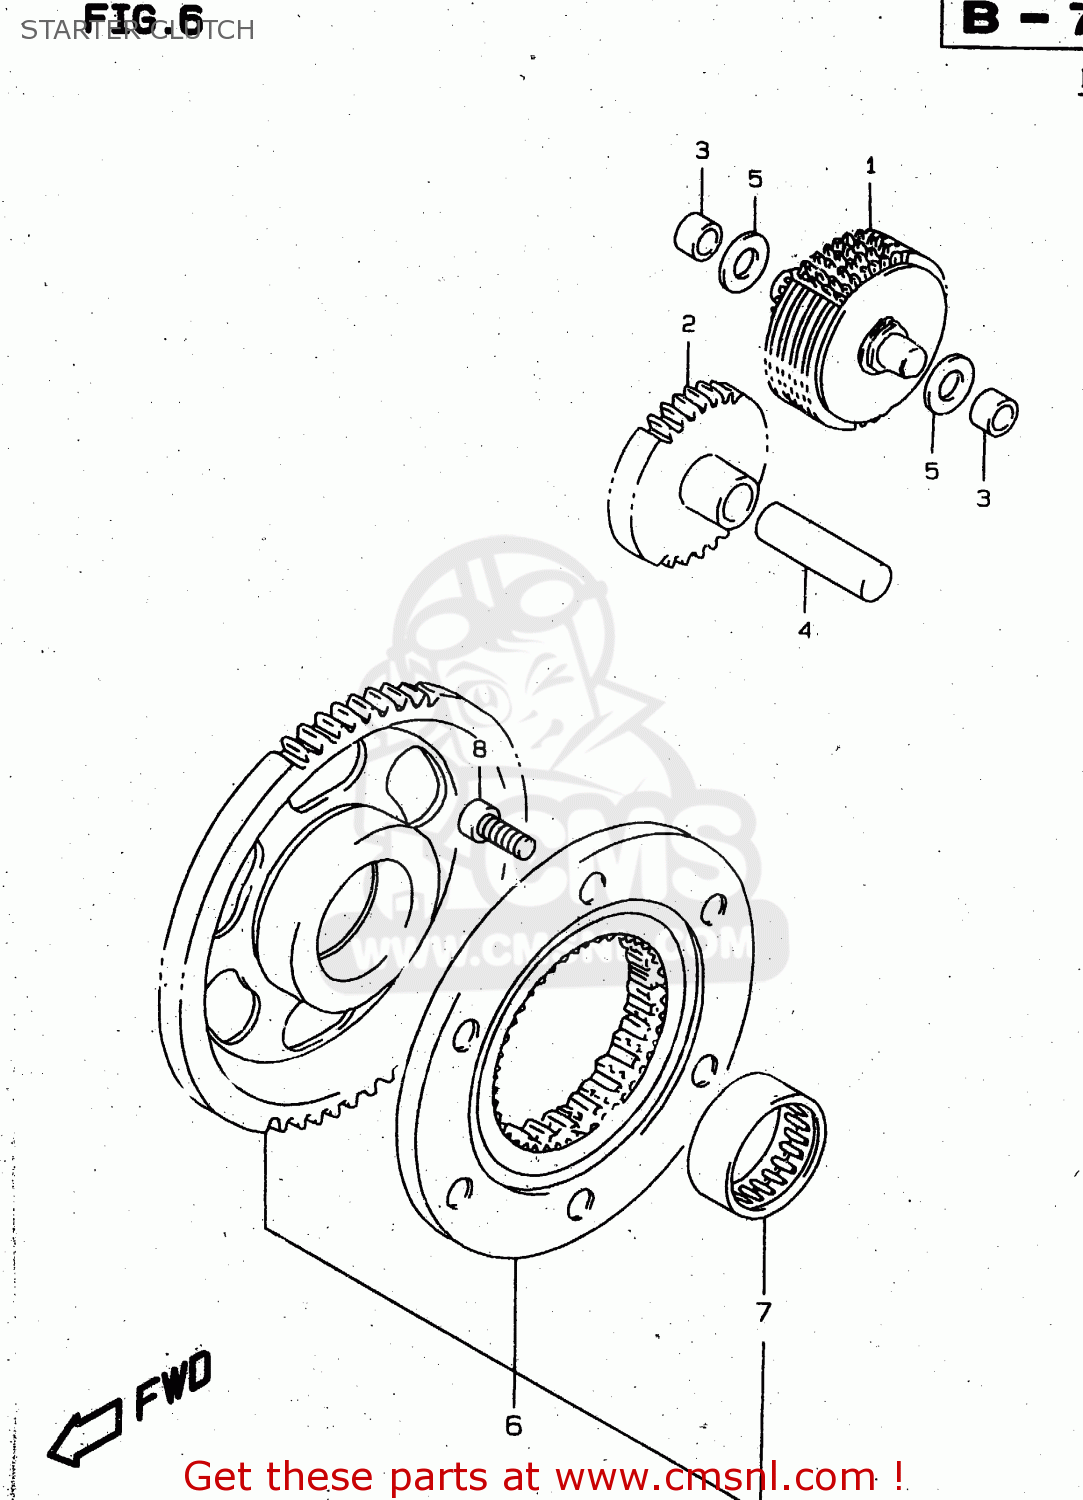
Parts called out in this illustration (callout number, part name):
1	LIMITER ASSEMBLY,STARTER IDLER GEAR
2	GEAR,STARTER IDLE NO.2(NT:27)
3	BUSH,LIMITER GEAR SHAFT
4	PIN
5	WASHER
6	CLUTCH SET,STARTER
7	BEARING(31X39X17.8)
8	BOLT
